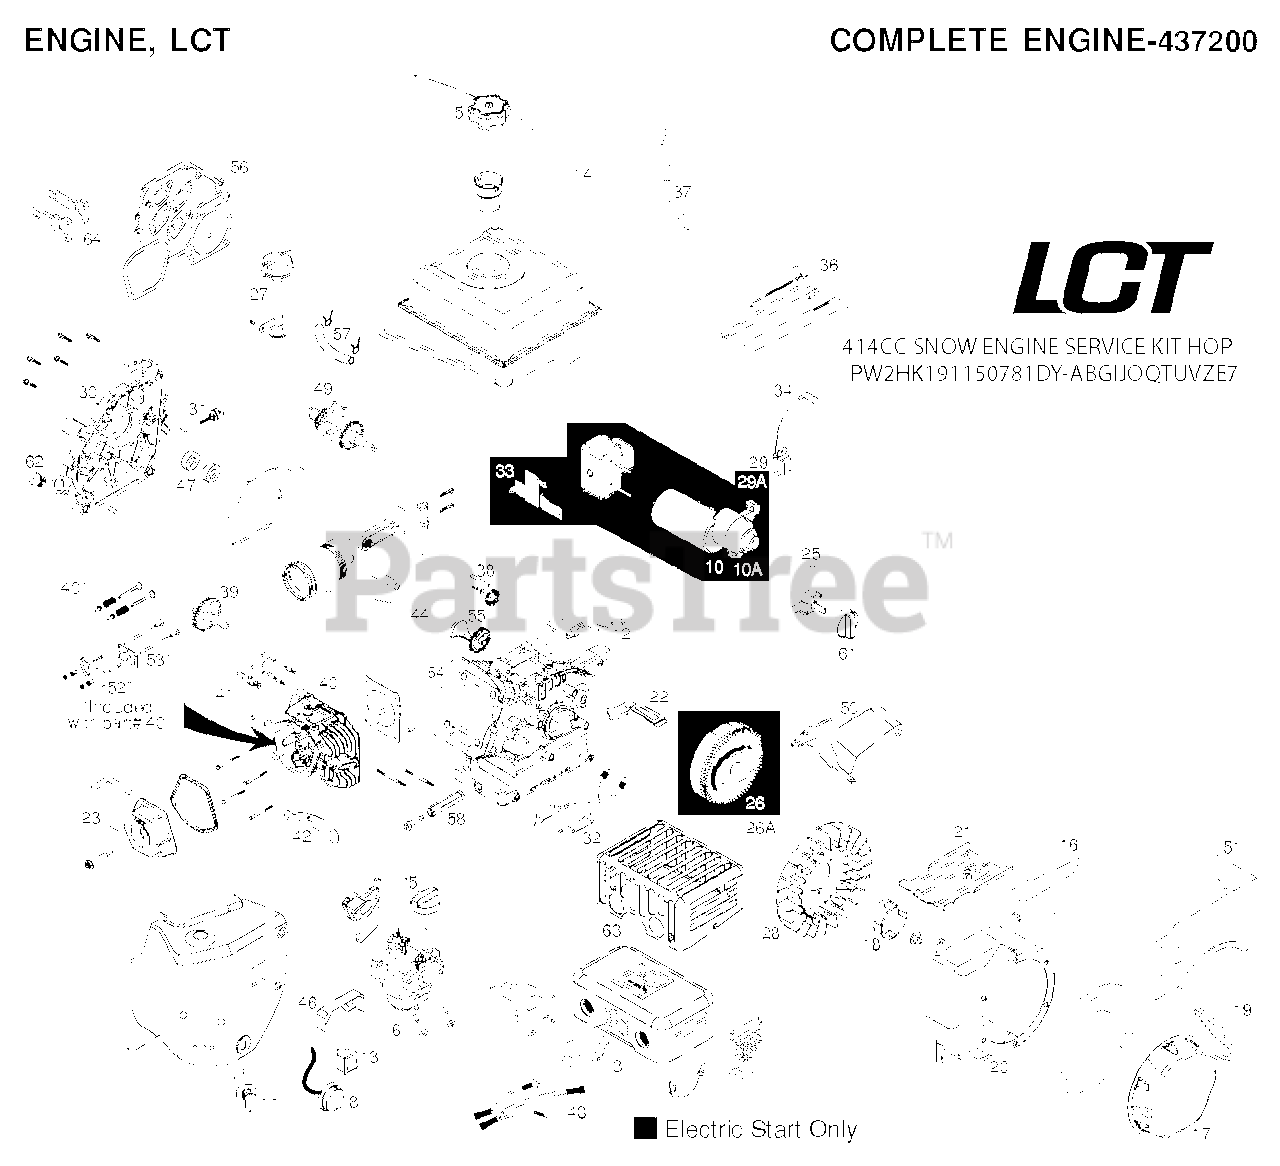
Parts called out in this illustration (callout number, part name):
1	HEATER.BOX.ASSY-SNW(SKSN4100)
3	MUFFLER.ASSY.SNOW(SKSN4200)
4	FUEL.TANK.ASSY.SNOW(SKSN4300)
5	FUEL.TANK.CAP.SNOW(SKSN4301)
6	CARBURETOR.ASSY.SNOW(SKSN4302)
8	PRIMER.BULB.ASSY(SKSN4304)
10	ELEC.START.ASSY.SNOW(SKSN4400)
10A	STARTER EUROPEAN 230V ELECTRIC
11	KEY.SWITCH.ASSY.SNOW(SKSN4401)
12	CDI.BOX.ASSY.SNOW(SKSN4404)
13	ON/OFF.SWITCH.SNOW(SKSN4403)
15	CHOKE.KNOW.SNOW(SKSN4500)
16	PLATE.GOVERN.LINK.S
17	RECOIL.START.ASSY.SNW(SKSN4600
18	STARTER.CUP.SML.SNOW(SKSN4601)
19	STARTER.GRIP.SNOW(SKSN4603.1)
20	BLOWER.HSG.ASSY.ELEC(SKSN4602
21	SHIELD.CYLINDER.SNOW(SK4141010
22	SHIELD.U/FYWHL.CHARG(SKSN4604)
23	VALVE.COVER.LCT.414CC.
25	FUEL.PETCOCK.SNOW(SKSN4900)
26	FLYWHEEL.ASSY.ELEC.START
26A	FLYWHEEL.ASSY.MAN.START
27	HIGHOIL.FILL.ASSY.KIT(SKSN4911
28	FLYWHEEL.FAN(SK4144000)
29	IGNITION COIL ASSY
29A	IGNITION.COIL.(CDI).291-414CC
30	CRANKCASE.CVR.ASSY(SK4143600)
31	DIPSTK.OIL.BLK.LCTSK4143711.1
32	CHARGING.COIL.AC/DC(SK4141710)
33	ELECTRIC.START.BRKT(SKSN4405)
34	SPARK.PLUG.BOOT.SNW,SKSN4691.1
36	GOVERNOR.ARM.ASSY(SKSN4502)
37	GOVERNOR.SHAFT(SK4143100)
38	GOVERNOR.GEAR.ASSY(SK4142900)
39	CAMSHAFT(SK4141600)
40	CYL.HEAD.ASSY.45 DEG.NON-GEN
41	SPARK.PLUG(SK2911550)
42	CDI.BOX.BRKT.SNOW(SKSN4402)
44	PISTON.AND.ROD.ASSY(SK4141400)
46	SHIELD.VAPOR(SKSN4606)
47	OIL SEAL KIT NON-GENERATOR
48	WIRE.HARNESS(SKSN4406)
49	CRANKSHAFT.KEYED
50	RP TOP SHIELD
51	SKIRT FUEL TANK
52	ROCKER ARM KIT
53	PUSH ROD TAPPET KIT
54	CYLINDER ASSY
55	COUNTER WEIGHT KIT
56	KIT.ENGINE GASKET.LCT.414CC
57	FUEL HOSE KIT
58	EXTENDED OIL DRAIN TUBE
61	FUEL KNOB-SNOW
62	NONREMVABLE.OIL.PLUG(SK4143715
63	CE COMPLIANT MUFFLER SHEILD
64	KEY SET(2 KEYS) SKSN0407.1
